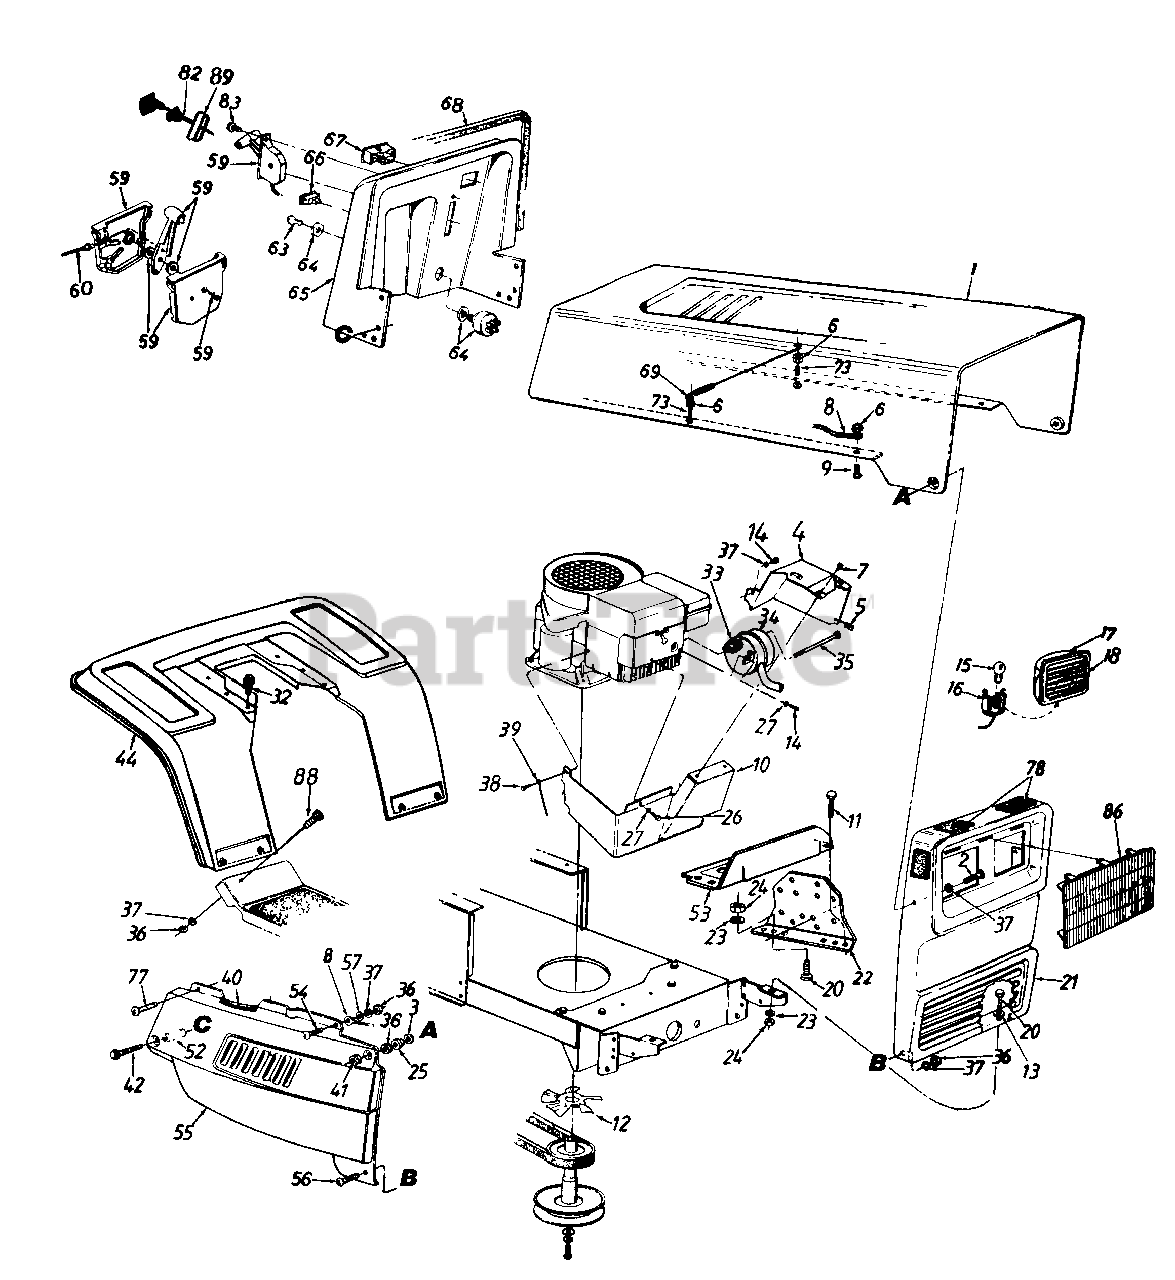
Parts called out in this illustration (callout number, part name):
1	Hood
2	Hex Bolt 1/4-20 x .88" Lg.
3	Washer .39" I.D. x .62"
4	Muffler Heat Shield - L.H.
5	Speed Nut #10-24 Thd.
6	Hex Sems Nut #10-24 Thd.
7	Hex B-Tap Scr. #10 x .38" Lg.
8	Hood Stop
9	Truss Hd. Scr. #10-24 x 1/2"
10	Muffler Heat Shield - Front
11	Hex Wash. Hd. B-Tap Scr. 5/16-18 x .5" Lg.
13	Fl-Wash. .344" I.D. x 1" O.D.
14	Hex Tap Scr. 1/4-20 x .5" Lg.
15	Bulb
16	Twist Lock - Bulb Socket
17	Headlight Housing
18	Lens
20	Hex Bolt 5/16-18 x .75" Lg.
24	Hex Nut 5/16-18 Thd.
25	Shld. Spacer
26	Hex Bolt 1/4-20 x 3/8" Lg.
27	Spr. Wash. 1/4" I.D.
33	Exhaust Gasket
34	Muffler (B & S)
35	Shoulder Bolt
36	Hex Nut 1/4-20 Thd.
37	L-Wash. 1/4" I.D.
38	Truss Mach. Scr. 5/16-18 x .75" Lg.
39	Ground Wire 7.5"
40	Trim Strip - 12"
41	Acorn Nut 1/4-20 Thd.
42	Hex TT-Tap Scr. 1/4-20 x 1.75" Lg.
57	Fl-Wash. .281" I.D. x .73" O.D.
59	Throttle Control Box Ass'y.
60	Throttle Control Wire (B & S)
63	Ignition Key
64	Ignition Switch
67	Ammeter
68	Trim Strip - 31"
69	Hood Spring
73	Hex Scr. #10-24 x 1.0" Lg.
77	Hex Wash. Hd. Tap Scr. 1/4 x .75" Lg.
78	Foam Strip 3/8 x 1-1/8" x 1-1/2 Lg.
82	Choke Control 29" Lg.
83	Truss Mach. AB-Tap Scr. #10 x .5" Lg.
86	Headlight Bezel
88	Truss Mach. Scr. 1/4-20 x .5" Lg.
89	Retainer Clip
17308A-0640	PANEL-SIDE RH - CO-OP GREEN (0640)
17308A-0691	PANEL-SIDE RH - BLACK JACK (0691)
17309A-0638	PANEL-SIDE-LH - MTD/TROY-BILT RED (0638)
17458A-0665	PANEL-SIDE RH - YARDMAN GREEN (0665)
17459A-0638	PANEL-SIDE-LH - MTD/TROY-BILT RED (0638)
